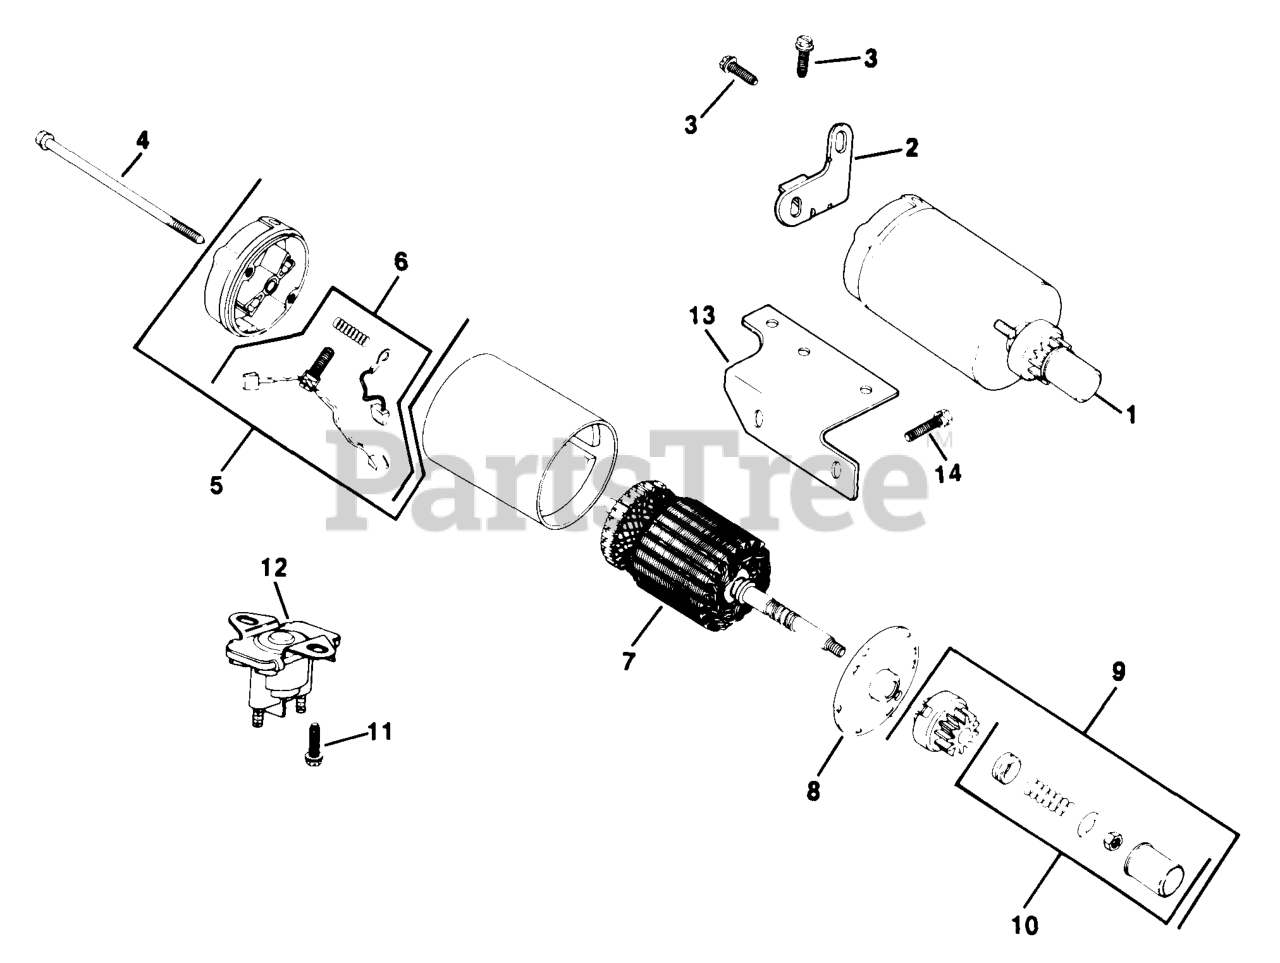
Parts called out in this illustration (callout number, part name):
1	STARTER - USE 41 098 06
2	BRACKET-(#DSC)
3	SCREW, WSH HD TAP 1/4-20X3/4" USE 25 086 100-S
4	BOLT, STARTER 1/4-20X5-1/16"-(#DSC)
5	CAP - USE 52 227 03
6	KIT - USE 82 755 28
7	ARMATURE - DISCONTINUED
8	CAP - USE 41 081 05
11	SCREW, WSH HD TAP 1/4-20X7/16" USE 25 086 106-S
13	BRACKET, SOLENOID
14	SCREW, SEMS 3/8-16-X1"
